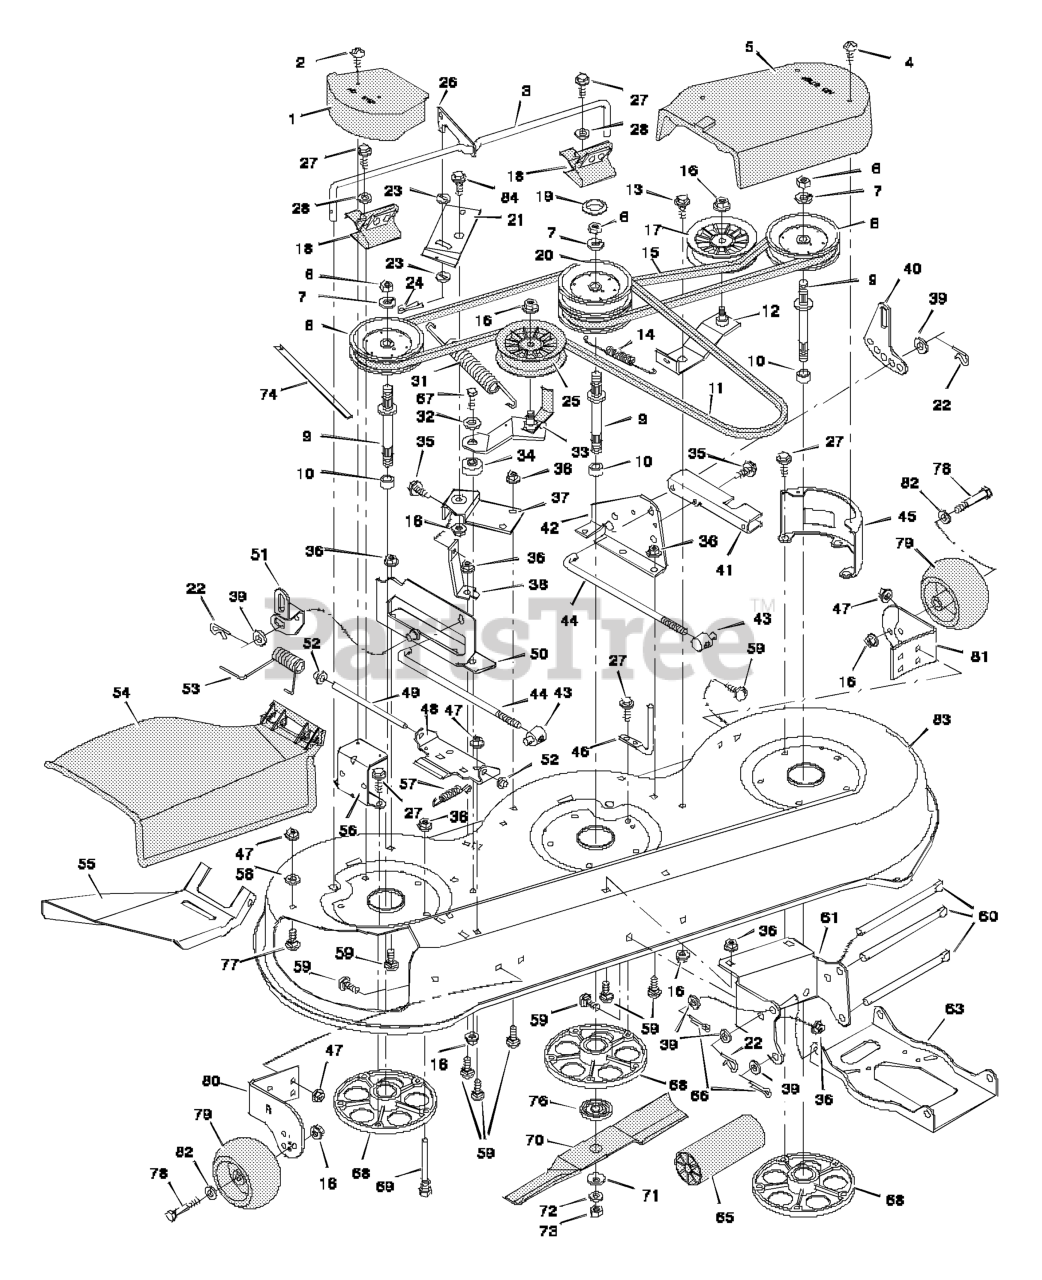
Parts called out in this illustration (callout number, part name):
1	Cover, Pulley
3	Rod, Brake
5	Cover, Left Pulley
6	Nut, Hex
7	Lockwasher
9	Jackshaft
10	Spacer, Bearing
11	Belt, Primary Mower Drive
12	Bracket, Idler
13	Bolt, Shoulder
14	Spring, Extension
15	Belt, Secondary Mower Drive
16	Locknut
17	Pulley, Idler
18	Spring Assembly, Brake
20	Pulley, Stack
21	Bracket, Pivot
22	Pin, Hair
24	Pin, Cotter
25	Pulley, Idler
26	Link, Brake
27	Screw
31	Spring, Extension
33	Bracket, Idler
34	Bushing
36	Nut, Hex
37	Support, Pivot
38	Strut, Pivot
40	Plate, Adjuster
41	Channel, Left Cover
42	Bracket Assembly, Lifter
43	NUT, Adjusting, 1/2-13
44	Rod, Adjuster
45	Bracket, Left Cover
46	Guide, Belt
47	Locknut
48	Bracket, Hinge
49	Rod, Deflector
50	Bracket Assembly, Lifter
51	Link, Suspension
52	Push- On Cap
53	Spring, Torsion
54	Deflector
55	Deflector, Inside
56	Bracket, Cover
57	Spring, Extension
59	Bolt, Carriage
60	Rod, Hanger
61	Bracket, Front Hanger
63	Hanger, Front
66	Pin, Cotter
67	Bolt, Hex
68	Housing, Mandrel
69	Guide, Belt
70	Blade (3 required)
71	Washer, Belleville
73	Nut, Hex
74	Indicator, Plastic
76	Adapter, Blade
77	Bolt, Carriage
78	BOLT, Gauge Wheel
79	Wheel, Gauge
80	Bracket, Right Gauge Wheel
81	Bracket, Left Gauge Wheel
82	Washer
83	Housing, Mower
84	Bolt, Shoulder
